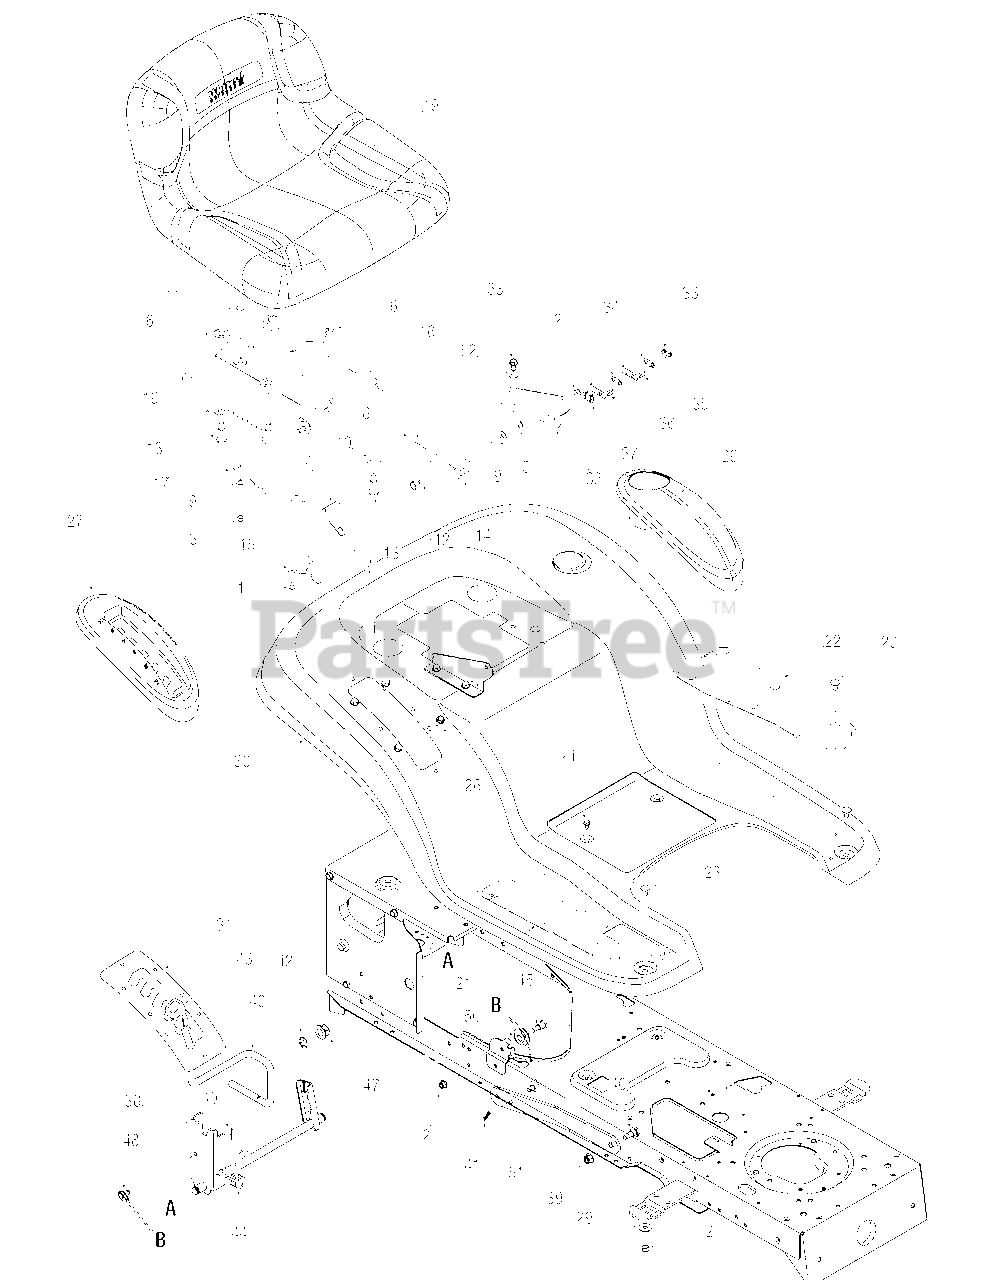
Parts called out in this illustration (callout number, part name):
1	Screw, #10-16 x.375
2	Nut, Flange Lock, 5/16-18
3	Nut, Flange Lock, 1/4-20
4	Seat Adjuster Grip
5	Nut, Speed,.3125 ID
7	Compression Spring,.41 x 1.5
8	Spring, Extension,.84 Dia. X 4.6
9	Wash, Flat,.344 x.688 x.065
10	Wash, Flat,.531x 1.062 x.134
11	Screw, Shoulder,.340 x.285,1/4-20
12	Screw, Shoulder, .437x.268 5/16-18
13	Screw, Shoulder,.50 x.925, 3/8-16
14	Seat Bracket, Lift
18	Seat Adjustment Selector
19	High Back Seat, Yellow
20	Ratchet Clip
21	RH Foot Pad, Rubber
22	LH Foot Pad, Rubber
23	Bolt, Carriage, 5/16-18,.62, Gr1
24	Screw, 1/4-20, 0.500
25	Screw, 5/16-12, 0.750
26	Screw, 1/4-15, 0.750
27	Cover, Lift Lever
28	Cover, w/ Cup Holder
29	Washer, Flat,.344 x 1.0 x .063
33	Screw, #8-18 x.50
34	Plate, Insulator
35	Spring Switch, Outer
36	Spring Switch, Inner
37	Plate, Insulator Boss
38	Shaft Assembly, Lift Service Kit
39	Nut, Flange Lock, 3/8-16
40	Pin, Cotter,.072 Dia. x 1.13
41	Pin, Cotter, 3/32, 1.0
42	Ring, E Type,.625 Dia.
43	Grip, Handle, 1/2
44	Spring, Torsion
45	Screw, 5/16-18 x.620 Gr2
46	Screw, Shld,.50 x.27, 3/8-16
47	Bearing, Hex Flange
48	Cable, Lift, 16.16
50	Pulley, Roller
52	Lock Washer, 5/16
53	Screw 5/16-18
